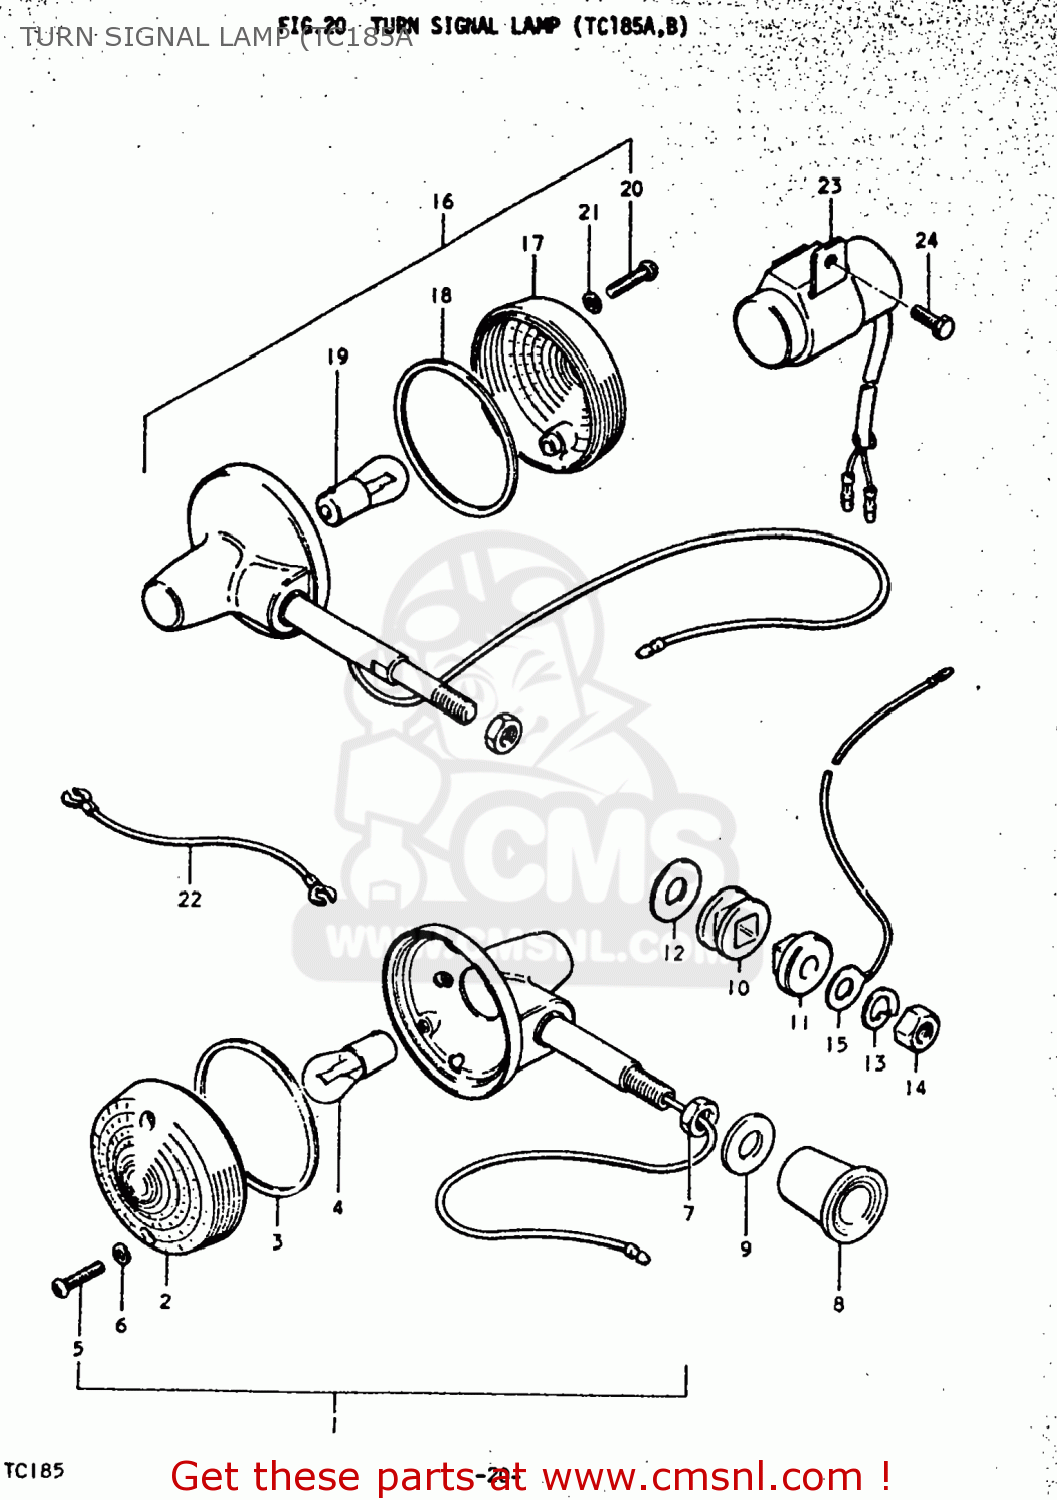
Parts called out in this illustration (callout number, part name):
1	LAMP ASSEMBLY,FRONT TURN SIGNAL
2	LENS
3	GASKET (NAS)
4	BULB(12V23W,STANLEY,A4577A)
5	SCREW
6	GASKET (NAS)
7	NUT
8	COVER,FRONT TURN SIGNAL BRACKET
9	WASHER
10	CUSHION
11	SPACER,RR TURNSIGNAL LAMP
12	WASHER (10.5X30X2.3)
13	LOCK WASHER
14	NUT
15	LEAD WIRE,EARTH
16	LAMP ASSEMBLY,REAR TURN SIGNAL
17	LENS
18	GASKET (NAS)
19	BULB(12V23W,STANLEY,A4577A)
20	SCREW
21	GASKET (NAS)
22	WIRE
23	RELAY,TURN SIGNAL
24	BOLT
